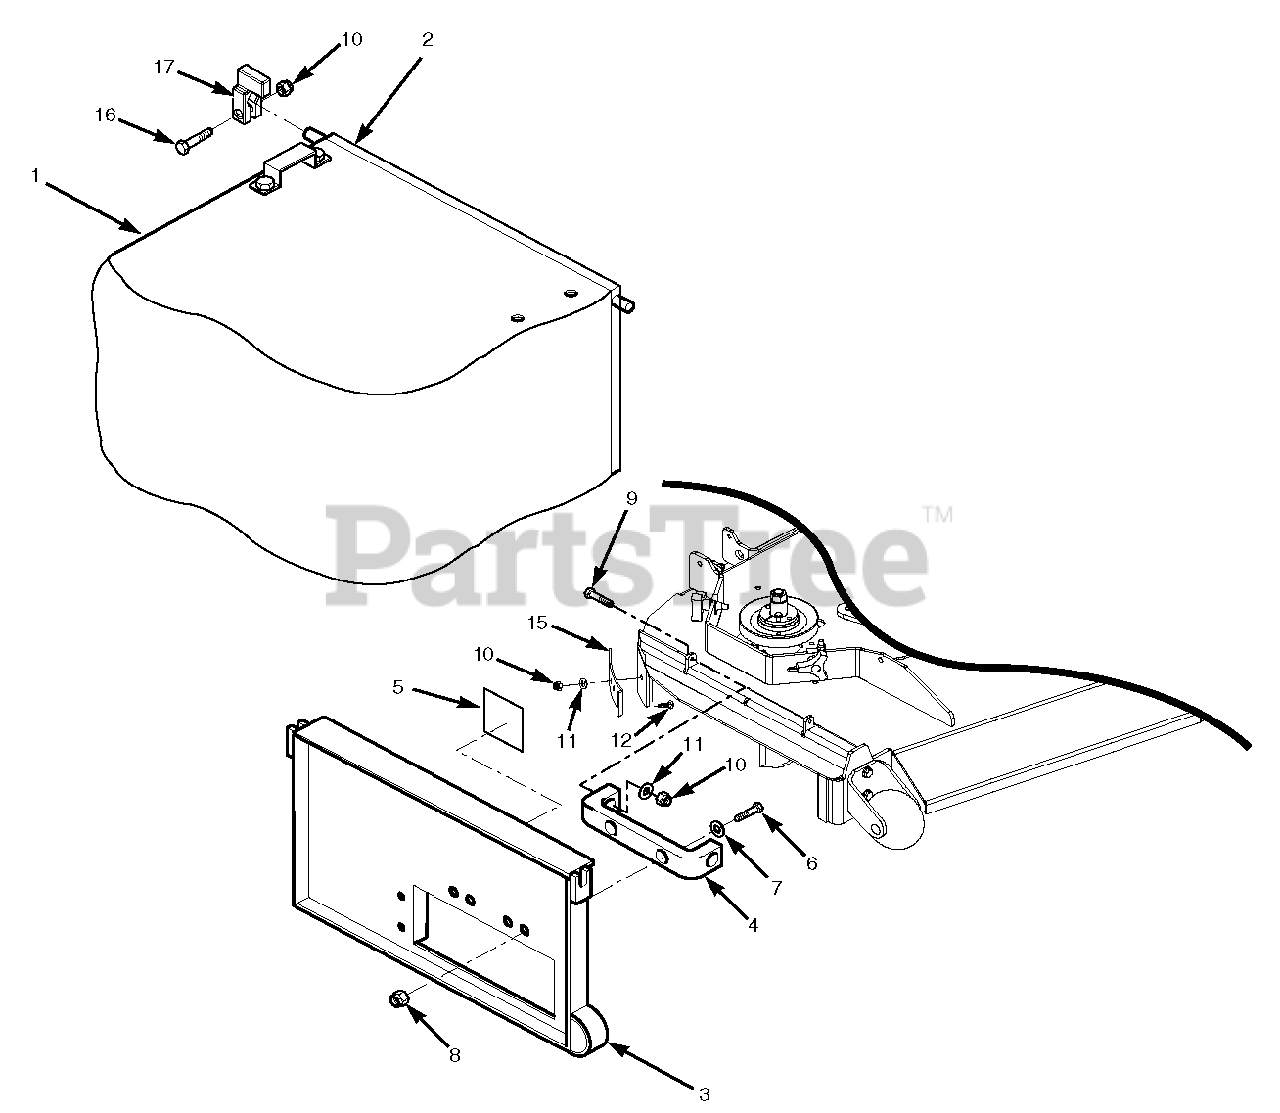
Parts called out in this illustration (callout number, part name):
1	Catcher Bag
2	Frame Weldment With Catcher Bag and Handle Assembly
3	Cover Weldment With Decal
4	Bracket, Mounting
5	Decal, Danger
6	Bolt, 3/8-16 x 1-1/2" Hex Head
7	Flat Washer, 3/8" (.391 x .938 x .105)
8	Nut, 3/8-16 Elastic Stop
9	Bolt, 5/16-18 x 1-1/4" Hex Head
10	Nut, 5/16-18 Elastic Stop
11	Flat Washer, 5/16" (.375 x .875 x .083)
12	Bolt, Carriage 5/16-18 x 3/4"
13	Bolt, Hex Head 1/4-20 x 3/4"
14	Nut, Elastic Stop 1/4-20
15	Filler Plate, Grass Catcher Velocity Plus Decks
16	Bolt, 5/16-18 x 1-1/2" Hex Head
17	Stop, Grass Catcher
